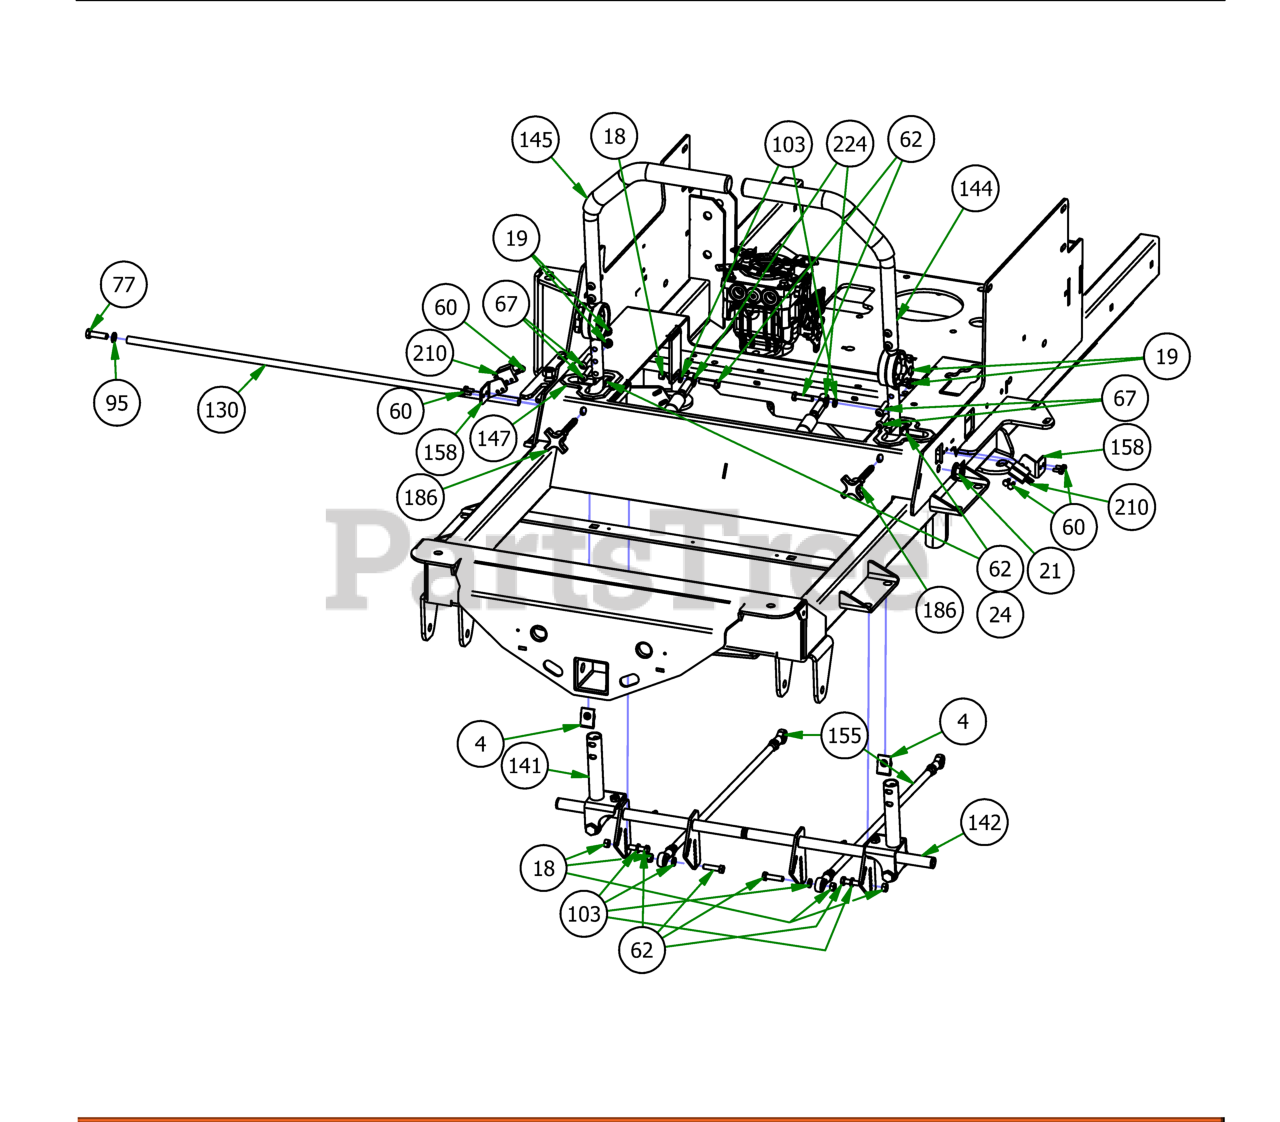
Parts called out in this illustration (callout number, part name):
4	Extruded Nut 3/8"-16 3/4" Hole Center With Patch
19	5/16-18 Nylock Insert Locknut
21	1/2-13 NYLON INSERT FLANGE LOCKNUT ZINC
24	5/16" Flange Nut
60	12-24x 1/2 HWH Bolt
62	5/16 x 1 1/4 Hex Bolt
67	5/16-18 UNC X 1-3/8" BHCS, TORX DRIVE, GR 5
77	3/8" x 1 1/4" Hex Bolt
95	3/8" Lock Washer
103	5/16" Lock Washer
130	2019 Steering Actuator Rod
141	2019 R Series RH Arm Rod Assembly
142	2019 R Series LH Arm Rod Assembly
144	2019 Left Hand ADJ. Steering Arm Kit
145	2019 Right Hand ADJ. Steering Arm Kit
147	Snap-In Bushing-2019
155	2019 Outlaw Gen2 XP Push Rod Assembly
158	2019 Arm Switch Bracket
172	2019 Rogue Right Pump 16cc
186	Speed Limiting Knob 3/8-16X 3"
206	2019 Veritical Suspension Frame
210	Safety Switch
224	2019 SROID Damper With Spherical Rod Ends
